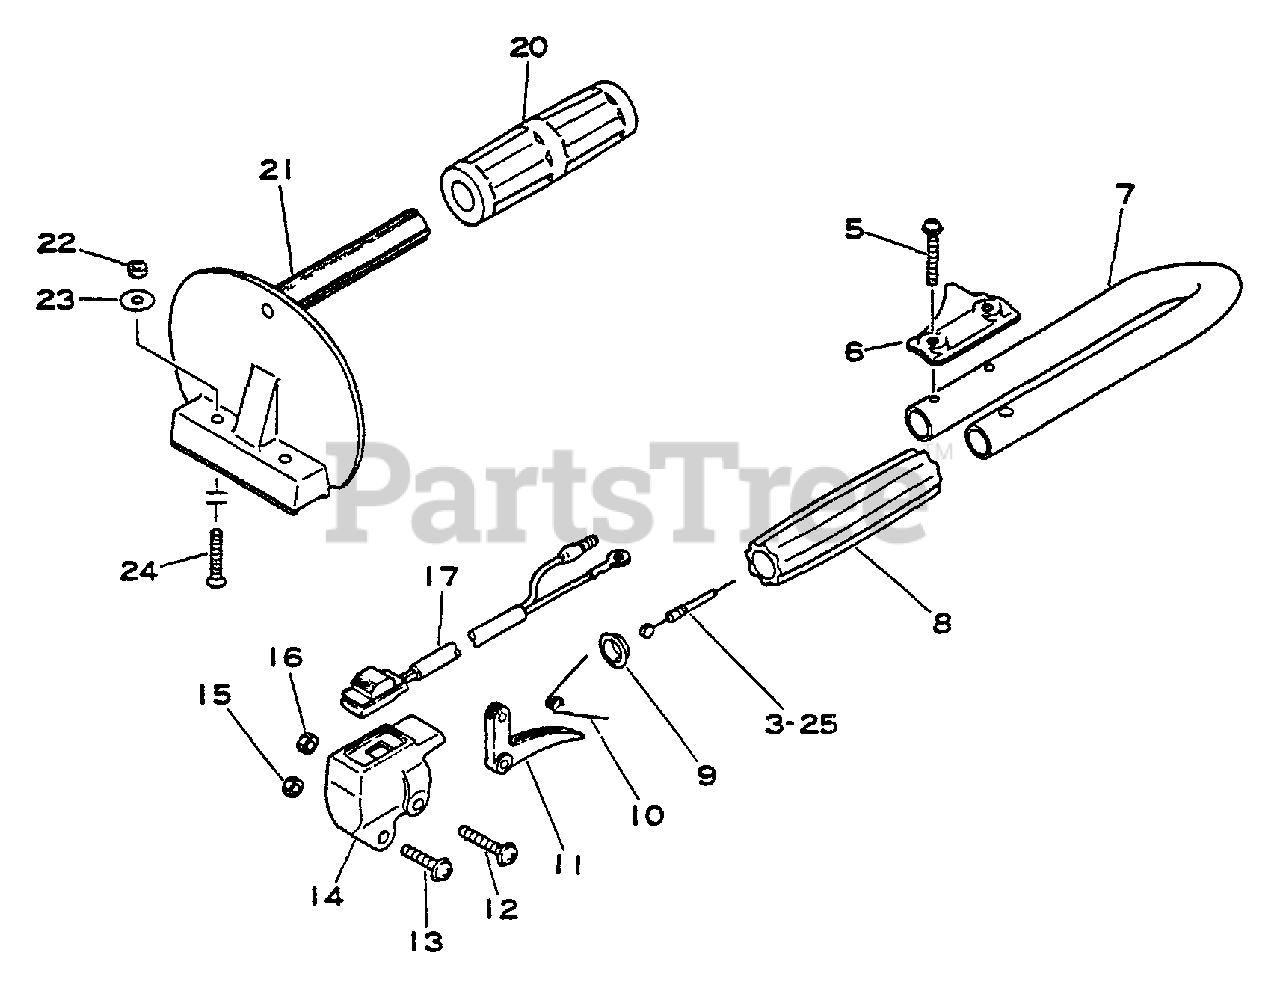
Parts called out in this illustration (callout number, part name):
5	SCREW - 5X35
6	BRACKET, HANDLE
7	HANDLE - REAR
8	GRIP, HANDLE
10	SPRING, TRIGGER
11	TRIGGER, THROTTLE
12	SCREW - 5X30
13	SCREW - 5X28
14	BRACKET, THROTTLE
16	LOCKNUT - 5
17	IGNITION SWITCH ASSY
20	GRIP, HANDLE
21	HANDLE - FRONT
22	LOCKNUT - 5
24	SCREW - 5X30
25	CABLE, THROTTLE
